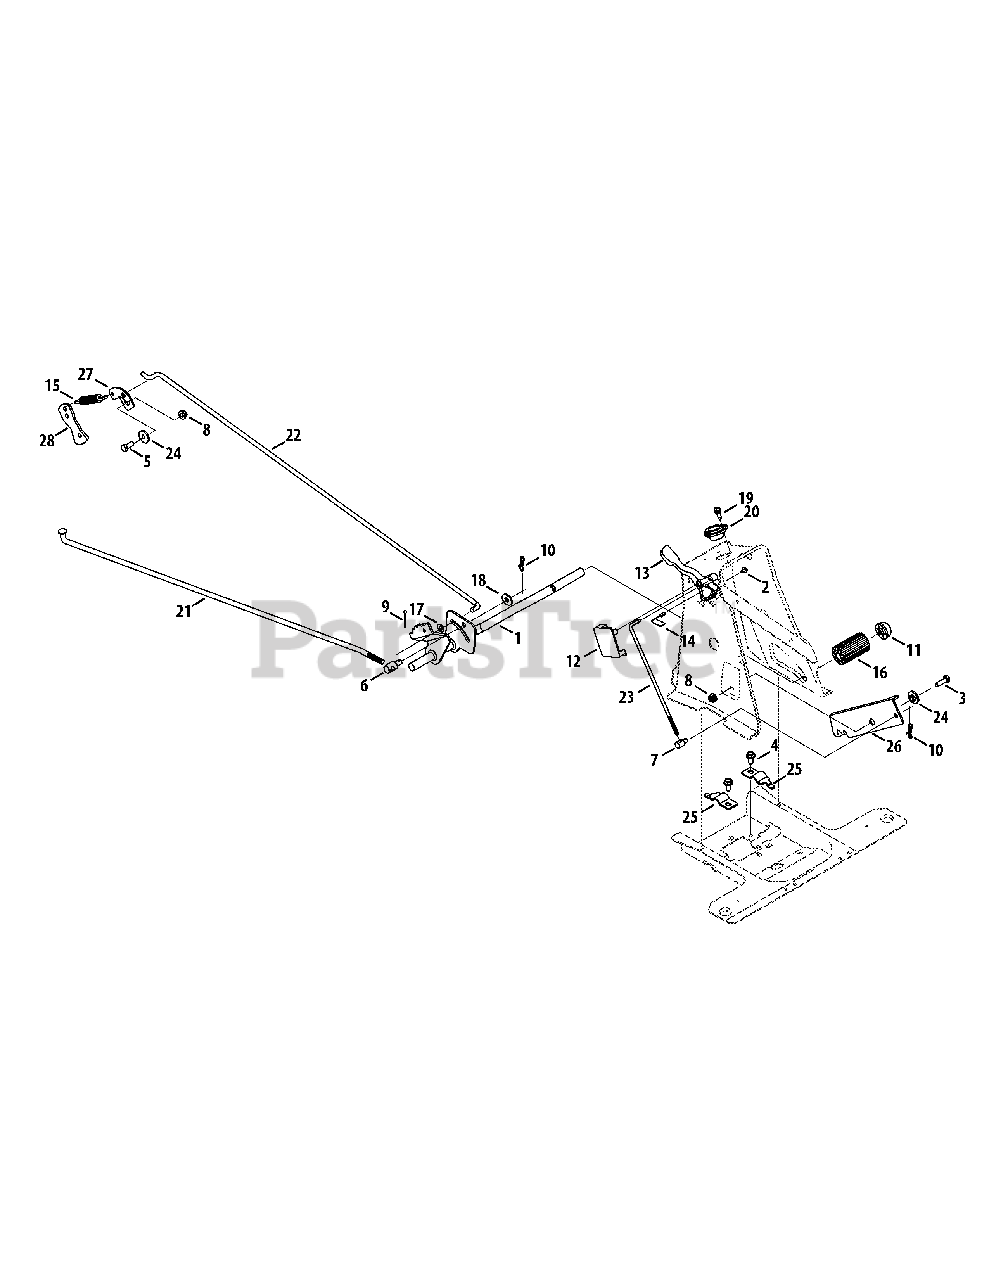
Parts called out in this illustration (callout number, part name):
1	Brake Pedal Assembly
2	Screw, #10-16 X 0.500
3	Hex Head Scerw, 5/16-18 X 1.00
4	Tap Screw, 5/16-18 X .750
5	Hex Head Screw, 5/16-18 X .75
6	Ferrule 3/8-24 X .375 Dia.
7	Adjustable Ferrule, 1/4-20 X 1.00
8	Flange Lock Nut, 5/16-18
9	Cotter Pin, 3/32X1.0
10	Bow-Tie Cotter Pin, 72
11	Push Cap, 5/8
12	Speed Control Cover
13	Speed Lever, 6-SPEED
14	Shift Spring
15	Extension Spring, .59 OD X 4.00 LG
16	Foot Pad, 2.5" LG.
17	Flat Washer, .330x.630x.064
18	Flat Washer, .380X.930X.110
19	Shoulder Screw, .368 X.113, 1/4-20
20	Steering Col. Bearing, .880 ID X 1.36
21	Variable Speed Control Rod
23	Speed Selector Control Rod
24	Shoulder Spacer
25	Pedal Strap Support Bracket, 5/8
26	Speed Latch Bracket
27	Brake Cam Bracket
28	Brake lever Bracket
